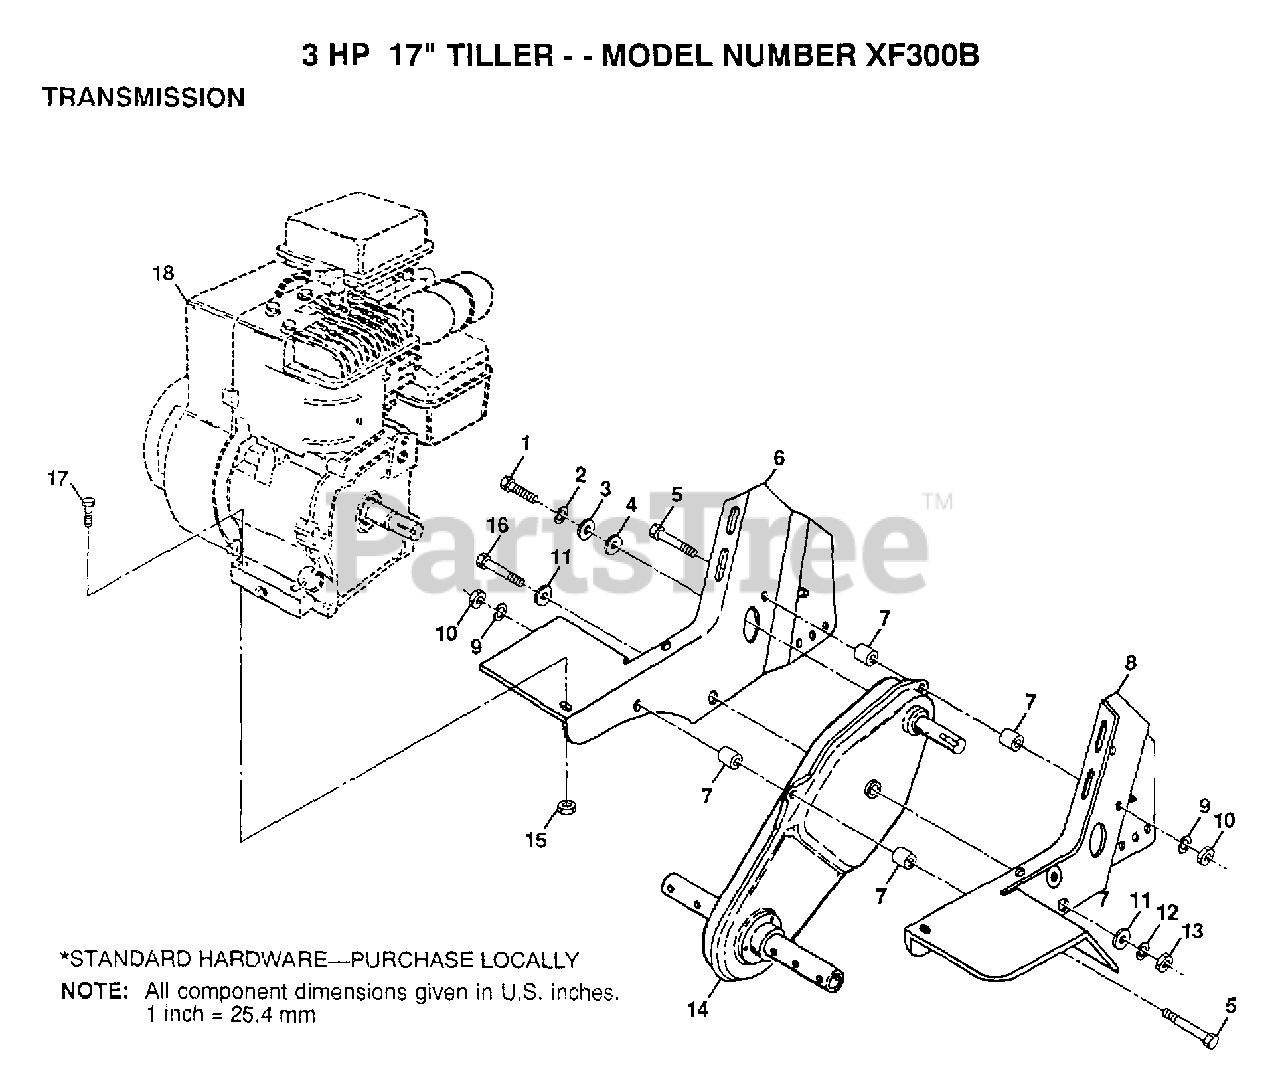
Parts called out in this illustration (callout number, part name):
1	BOLT
2	LOCKWASHER
3	WASHER
4	WASHER
6	"BRKT,ENG RH"
7	SPLIT SPACER RT
8	ENGINE BRKT LH
9	LOCKWASHER
10	NUT.HEX.5/16-18
11	WASHER
12	LOCKWASHER
13	GRIPCO NUT
16	BOLT.3/8-24X3.75
17	BOLT.HEX.5/16-1.5
18	ENGINE, B&S
